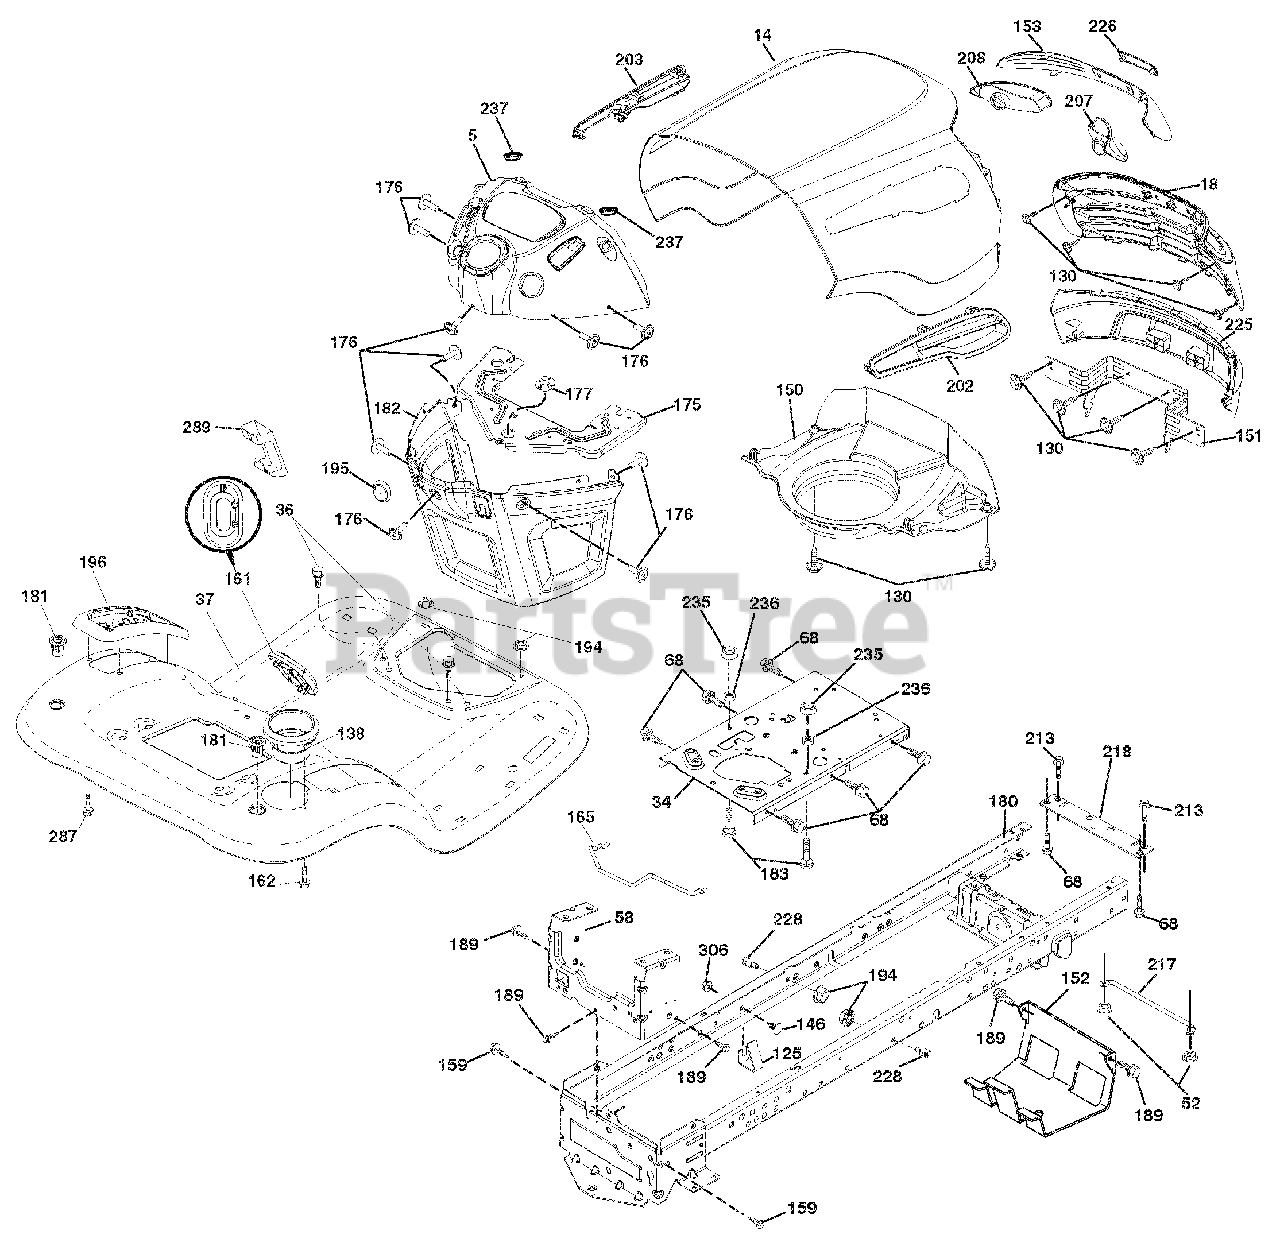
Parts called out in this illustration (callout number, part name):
5	DASH P/L TEX CABLE
18	GRILLE ELITE ARIENS BLACK
34	PLATE.ENGINE.WELDED.CHASSIS
36	SCREW.5/16-18X3/4.SMGML.TAP/R
37	FENDER TLT W/CPH W/FW
52	Nut, Hex, Crownlock 5/16-18
58	DRAWBAR.UPPER.2PC.SML.FENDER
68	SCREW.THDROL.5/16-18 X 1/2TYTT
125	CLIP.FUEL.LINE
138	CUPHOLDER TL TEX 428
150	AIR DUCT
151	BRACKET.PIVOT
152	SHIELD.BROWNING.W/TEX
153	LENS.BAR
159	SCREW.HEXWSH THDR3/8-16X3/4.BL
161	WINDOW FUEL
162	SCREW.HEX.WSH.HI-LO.1/4X1/2UNC
165	SUPPORT.TANK.REAR.W/TEX
175	CROSSMEMBER.LT
176	SCREW.#10-24X5/8.RND.QUDRX.GIM
177	BUSHING.STEERING.LT
180	CHASS.WLDMT.TL.12GA/2PC.18/22"
181	BUSHING MNT FEND CRGO BLK TEX
182	DASH.LOWER.LT.CCS
183	BOLT.FIN.HEX.5/16-18 UNC X1-1/
189	SCREW.5/16-18X3/4.SMGML.TAP/BL
194	Nut, Lock Hex Flange 5/16-18 u
195	PLUG HOLE DASH TOWER
196	CONSLE.ASM.DECK.LFT.BL/RBT.TLT
202	VENT.SIDE.LH
203	VENT RH
207	BEZEL.RH
208	BEZEL.LH
213	BOLT.HEX.HD.1/4-20UNC X 3/4
217	ROD.PIVOT.HOOD
218	X-PIECE.HOOD.STOP.NON/STEALTH
226	ARIENS.LOGO.PLATE
228	STUD.FASTNER.W/'D'ANTI-ROTATIO
235	SPACER.FENDER
236	NUT.CENTER LOCK.5/16-18 UNC
237	PLUG.MOUNT.CARGO
287	SCREW.HEX.WASHEAD.1/4-20 X 3/8
289	PLUG.CRUISE.CONTROL
306	Nut, Hex, Flangelock 3/8-16
